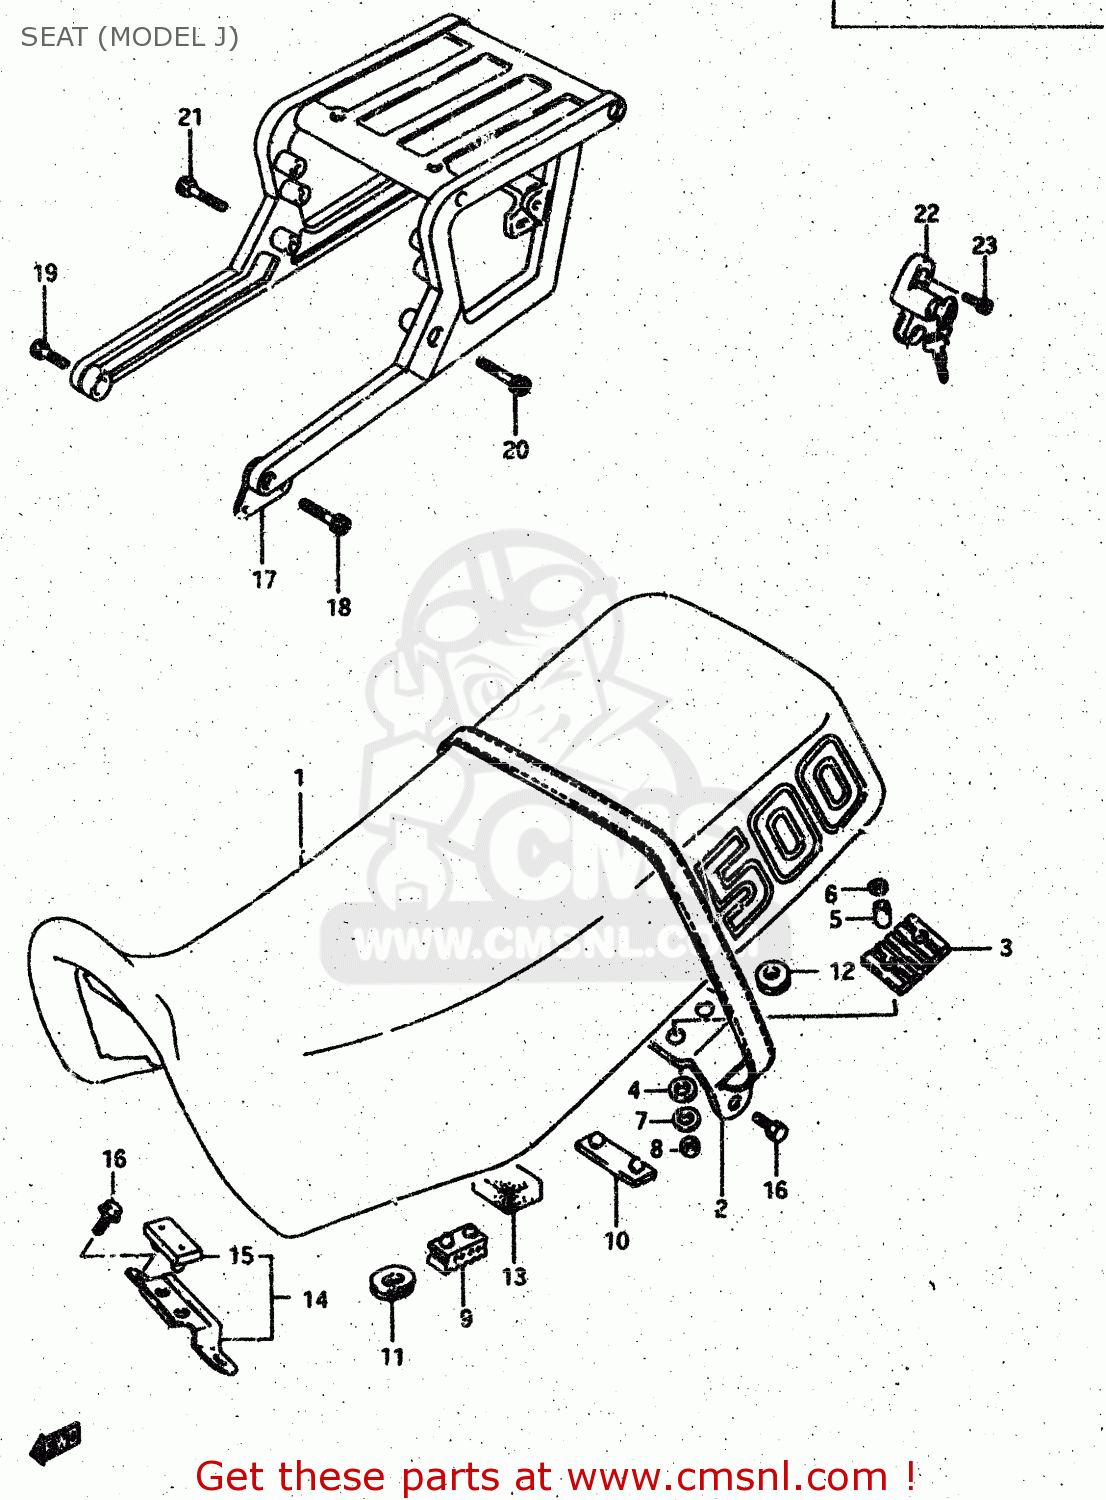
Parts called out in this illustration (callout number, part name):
1	SEAT SET (BLUE)
2	BAND,SEAT
3	CUSHION,SEAT FR
4	CUSHION,FR PLATE
5	SPACER,SEAT SUPPORT
6	WASHER
7	WASHER, LOWER
8	NUT
9	CUSHION,SEAT(40X20X15)
10	CUSHION
11	CUSHION
12	CUSHION
13	CUSHION,TOOL(40X30X15)
14	PLATE ASSY,SEAT FR HOOK
15	CUSHION
16	BOLT
17	CARRIER ASSEMBLY,REAR
18	BOLT, FRONT LH
19	BOLT, FRONT RH
20	BOLT ,8X50
21	BOLT, REAR RH
22	LOCK SET,HELMET
23	BOLT
